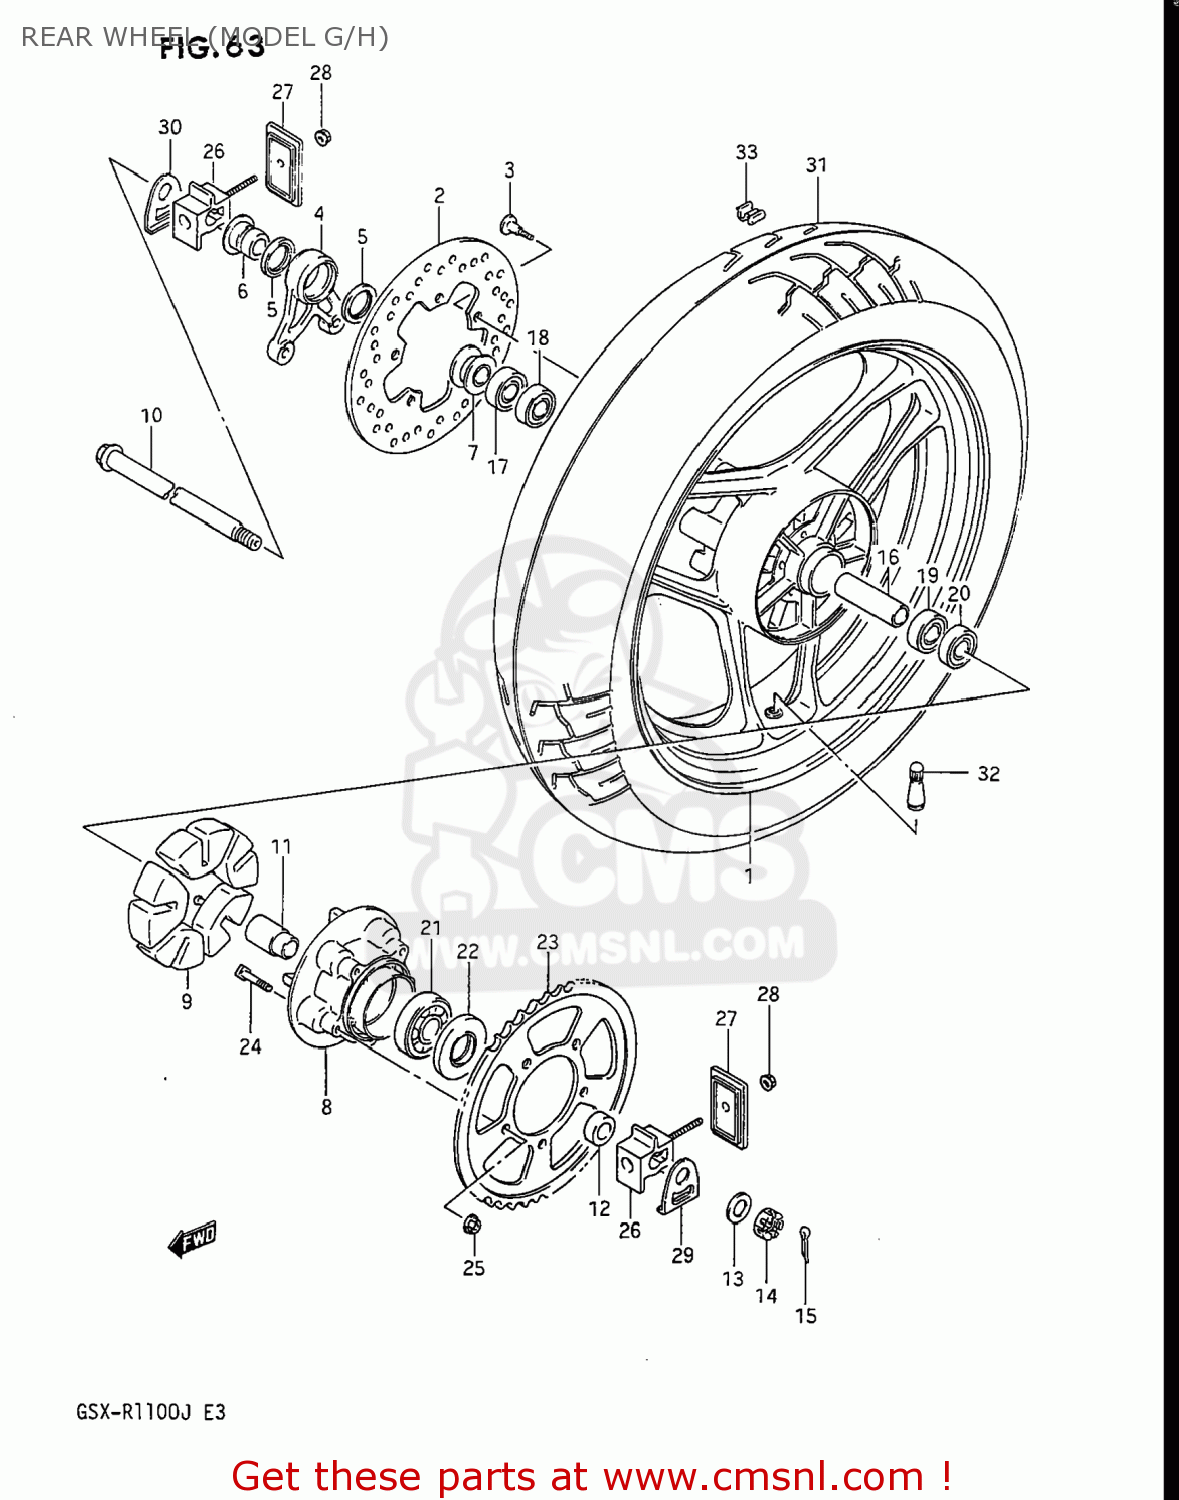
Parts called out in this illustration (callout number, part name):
1	WHEEL,REAR (MT4.00X18)
2	DISC,RR BRAKE
3	BOLT
4	BRACKET,RR CALIPER
5	SEAL,OIL(28X35X5)
6	SPACER,RR CALIPER BRACKET
7	SPACER,RR AXLE,R
8	DRUM,REAR SPROCKET MOUNT
9	ABSORBER,RR HUB SHOCK
10	AXLE,REAR
11	RETAINER,RR HUB BEARING
12	SPACER,RR AXLE,L
13	WASHER
14	NUT
15	PIN, COTTER
16	SPACER,REAR WHEEL HUB
17	BALL BEARING
18	BEARING
19	BEARING
20	BEARING
21	BEARING(25X62X17)
22	SEAL,OIL(35X62X8)
23	SPROCKET,REAR (NT:47)
24	BOLT(10X44)
25	NUT
26	ADJUSTER,CHAIN
27	PLATE,CHAIN ADJUSTER GUIDE
28	NUT
29	WASHER,CHAIN ADJUSTER
30	WASHER,CHAIN ADJUSTER
31	TIRE 150/70R18 (T/L)
32	VALVE,TIRE
33	BALANCER,WHEEL
